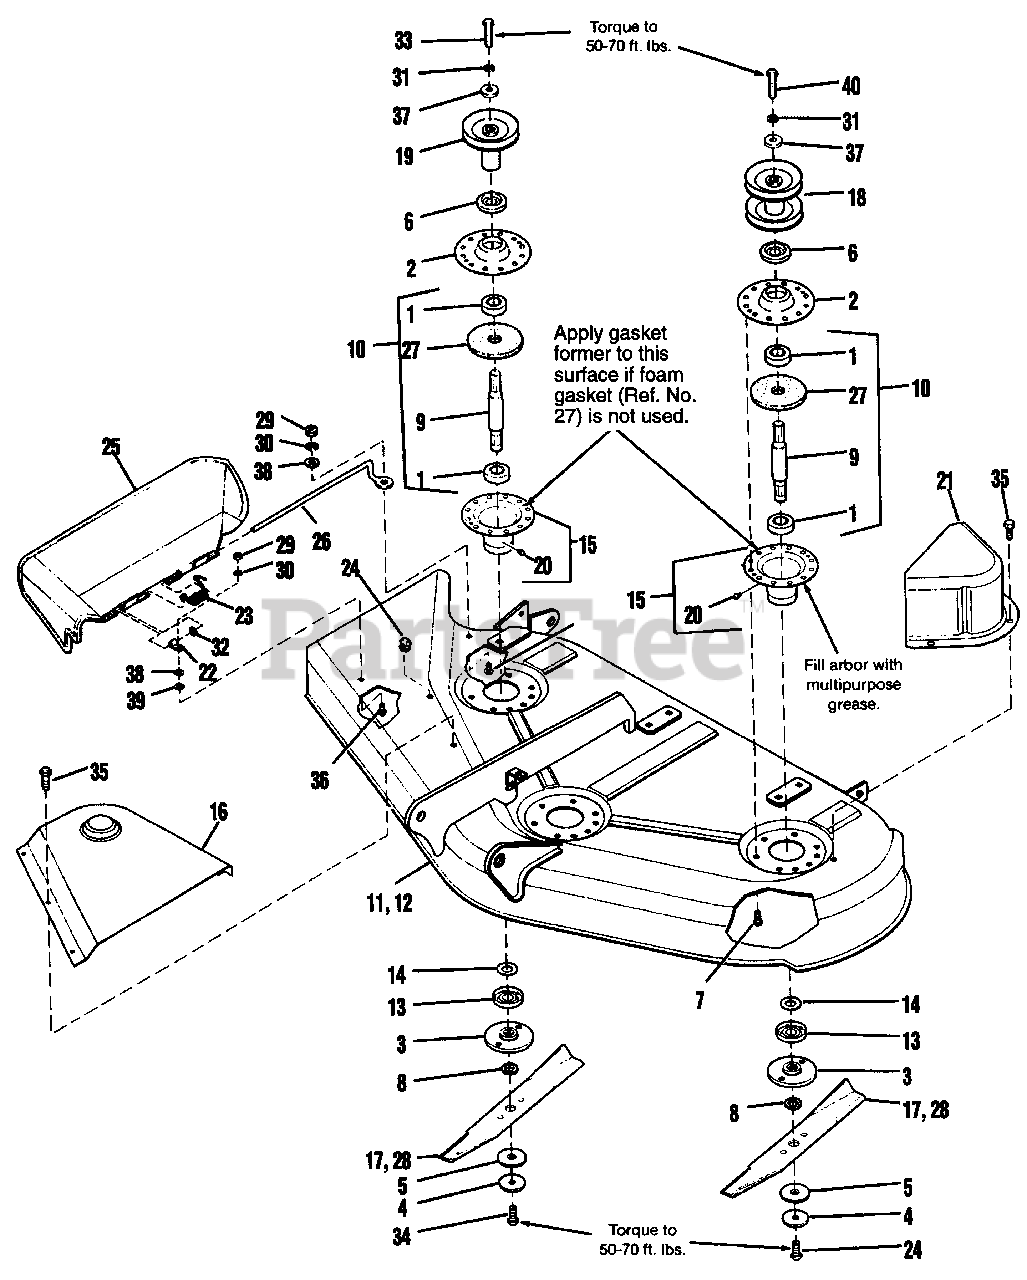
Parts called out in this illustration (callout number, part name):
2	HOUSING, Arbor, Top
3	ADAPTOR, Blade
4	WASHER, Spring
5	WASHER, Spline
6	SHIELD, Bearing Upper, Arbor
7	SCREW, Hex, Taptite, 5/16 x 3/4
8	COLLAR, Mower Arbor
9	SHAFT, Arbor (Incl. Ref. No. 8)
10	SHAFT & BEARING ASSY. (Center & Outer)(Incl. Ref. Nos. 1, 9, & 27)
11	HOUSING ASSY., 44" (Orange)
11	HOUSING ASSY., 44" (Black)
12	HOUSING ASSY., 50" (Orange)
12	HOUSING ASSY., 50" (Black)
13	SHIELD, Grass, Bottom
14	WASHER, Shim
15	HOUSING ASSY., Arbor, Bottom (Incl. Ref. Nos. 15 & 20)
16	COVER, Arbor
17	BLADE, Mower, 16-1/8
18	PULLEY ASSY.
19	PULLEY ASSY., Deck Drive
20	GREASE FITTING
21	COVER, Arbor
25	DEFLECTOR, Plastic
26	ROD, Deflector, Front
27	GASKET, Foam
28	BLADE, Mower, 50"
29	NUT, Hex, 1/4-20 ESNA
31	LOCKWASHER, 7/16
32	WASHER, Plain, 5/16
33	CAPSCREW, Hex Hd., 7/16-14 x 1-1/4
34	CAPSCREW, Hex Hd., 7/16-14 x 1
35	SCREW, Hex, Taptite, 5/16 x 1/2
36	CARRIAGE BOLT, 1/4-20 x 7/8
37	WASHER, Plain
38	WASHER, Flat
39	NUT, Push On
40	CAPSCREW, Hex Hd., 7/16-14 x 3-1/4
